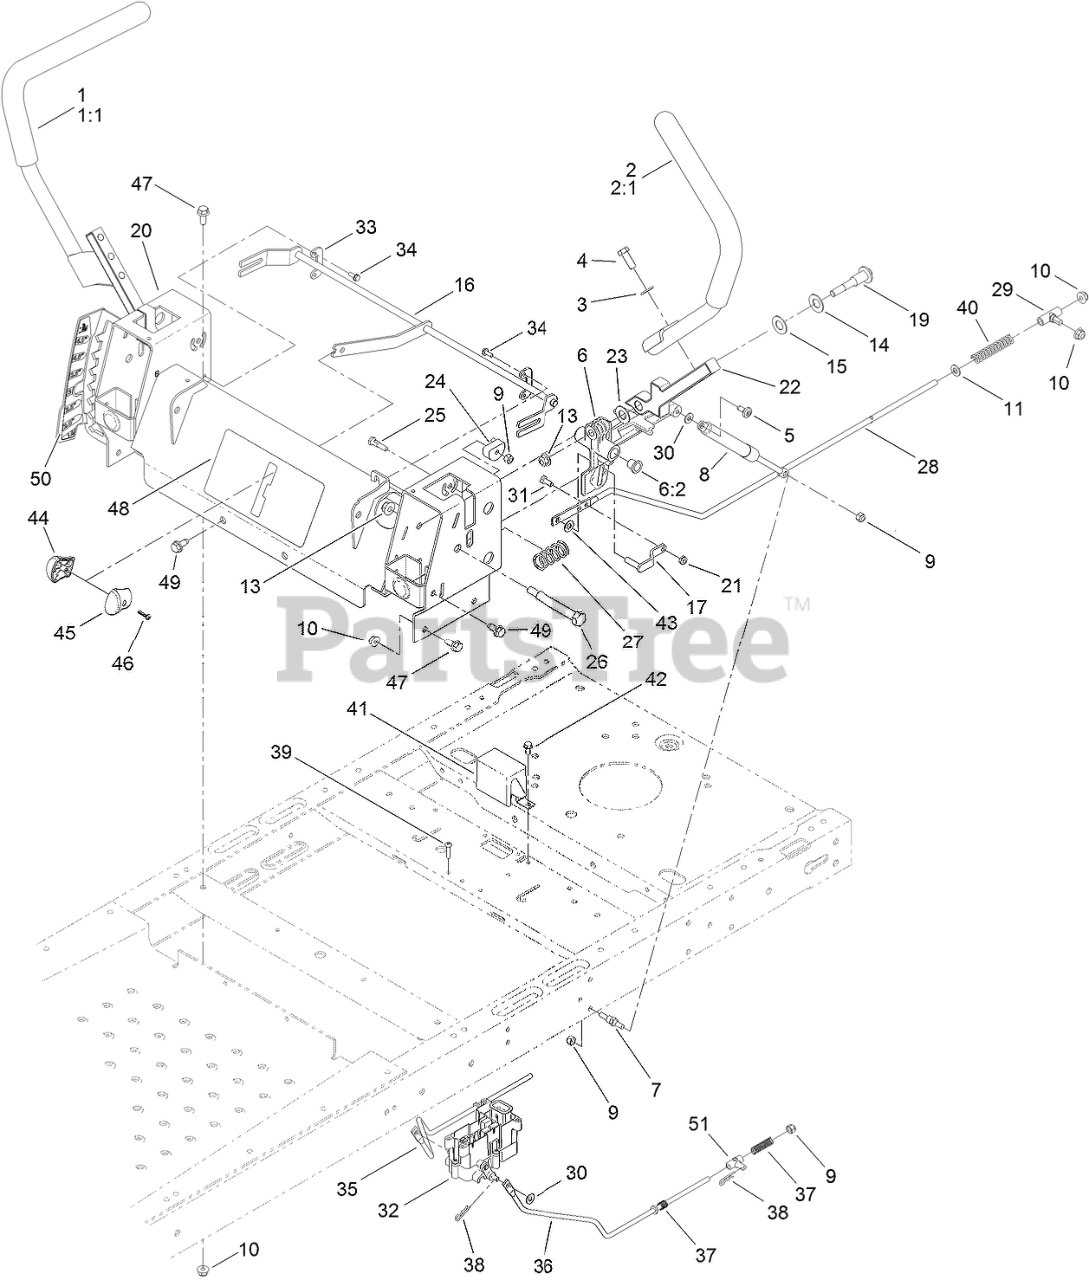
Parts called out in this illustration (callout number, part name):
1	HANDLE-CONTROL, RH
2	HANDLE-CONTROL, LH
3	WASHER-FLAT
4	SCREW-HH
5	SCREW-SHOULDER
6	ACTUATOR ARM ASM
6:2	BUSHING-FLANGE
7	STUD-DAMPER
8	Damper-Control, Motion
9	NUT-LOCK, NI
10	NUT-HF, NI
11	WASHER-PLAIN
13	NUT-HF, NI
14	WASHER-BELLEVILLE
15	WASHER
16	CONTROL-SPEED
17	PIN-ROD, HYDRO
19	BOLT-PIVOT
20	BOX-CONTROL
21	NUT-LOCK, NI
22	LEVER-CONTROL
23	WASHER-NYLON
24	ECCENTRIC
25	BOLT-PIVOT, ECCENTRIC
26	BOLT-PIVOT
27	SPRING-RETURN
28	ROD-HYDRO
29	MOUNT-ROD, HYDRO
30	WASHER
31	SCREW-HH
32	BRAKE CONTROL MODULE ASM
33	RETAINER
34	SCREW-TAPTITE
35	ROD-BRAKE, RH
36	ROD-BRAKE, LH
37	SPRING-COMPRESSION
38	PIN-COTTER
39	SCREW-PPH
40	SPRING-RETURN, NEUTRAL
41	COVER-BRAKE
42	SCREW-HWH
43	SPACER-NYLON
44	KNOB-RH
45	KNOB-LH
46	SCREW-PPH
47	SCREW-HHF
48	DECAL-SPEED CONTROL
49	SCREW-HWHTF
50	DECAL-HOC
51	MOUNT-PIVOT
